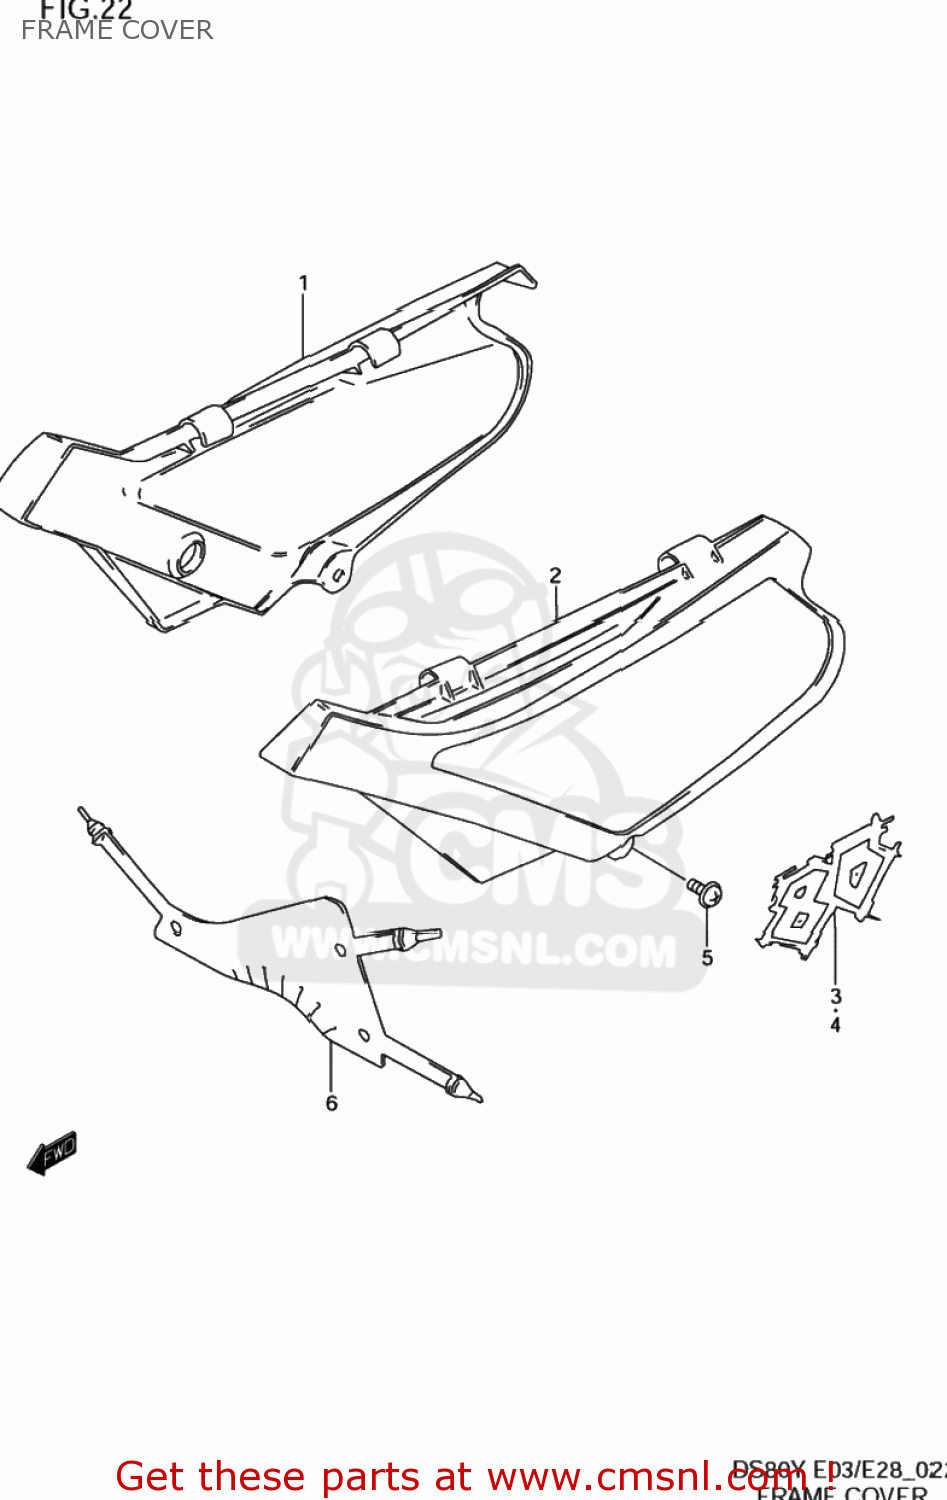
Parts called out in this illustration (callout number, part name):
1	COVER,FRAME,RIGHT
2	COVER,FRAME,L(WHITE)
3	EMBLEM,FRAME COVER
4	EMBLEM,FRAME COVER
5	SCREW(6X16)
6	MUD GUARD,FRAME COVER
